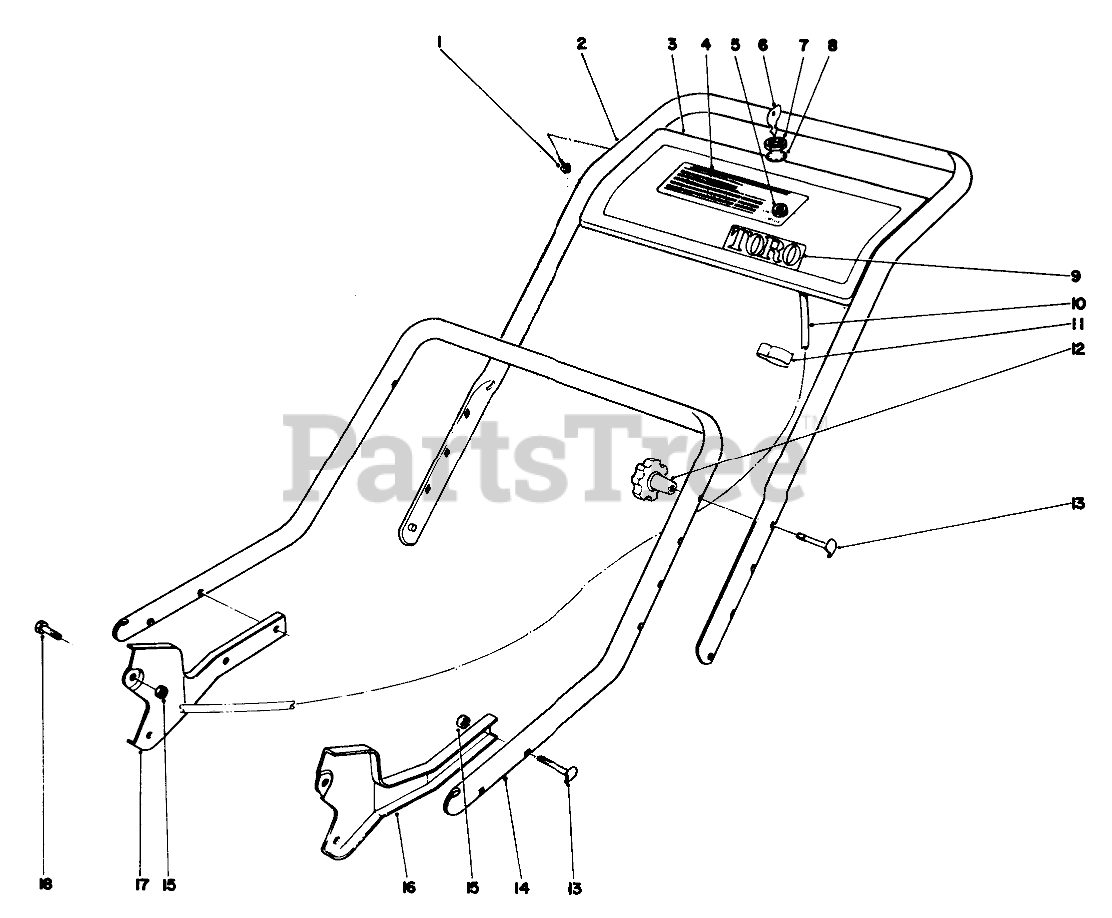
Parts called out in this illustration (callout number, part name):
1	SCREW-HWHTF
2	Upper Handle
3	Control Plate
4	Decal-Control Plate
5	Switch
6	Key
7	NUT-HH
8	WASHER-TOOTH, INTERNAL
9	Decal Toro
10	Wire Harness
11	BOWDEN CLIP
13	HANDLE SCREW
14	Lower Handle
15	Nut
16	Latch Handle L.H.
17	Latch Handle R.H.
18	SCREW-HH
